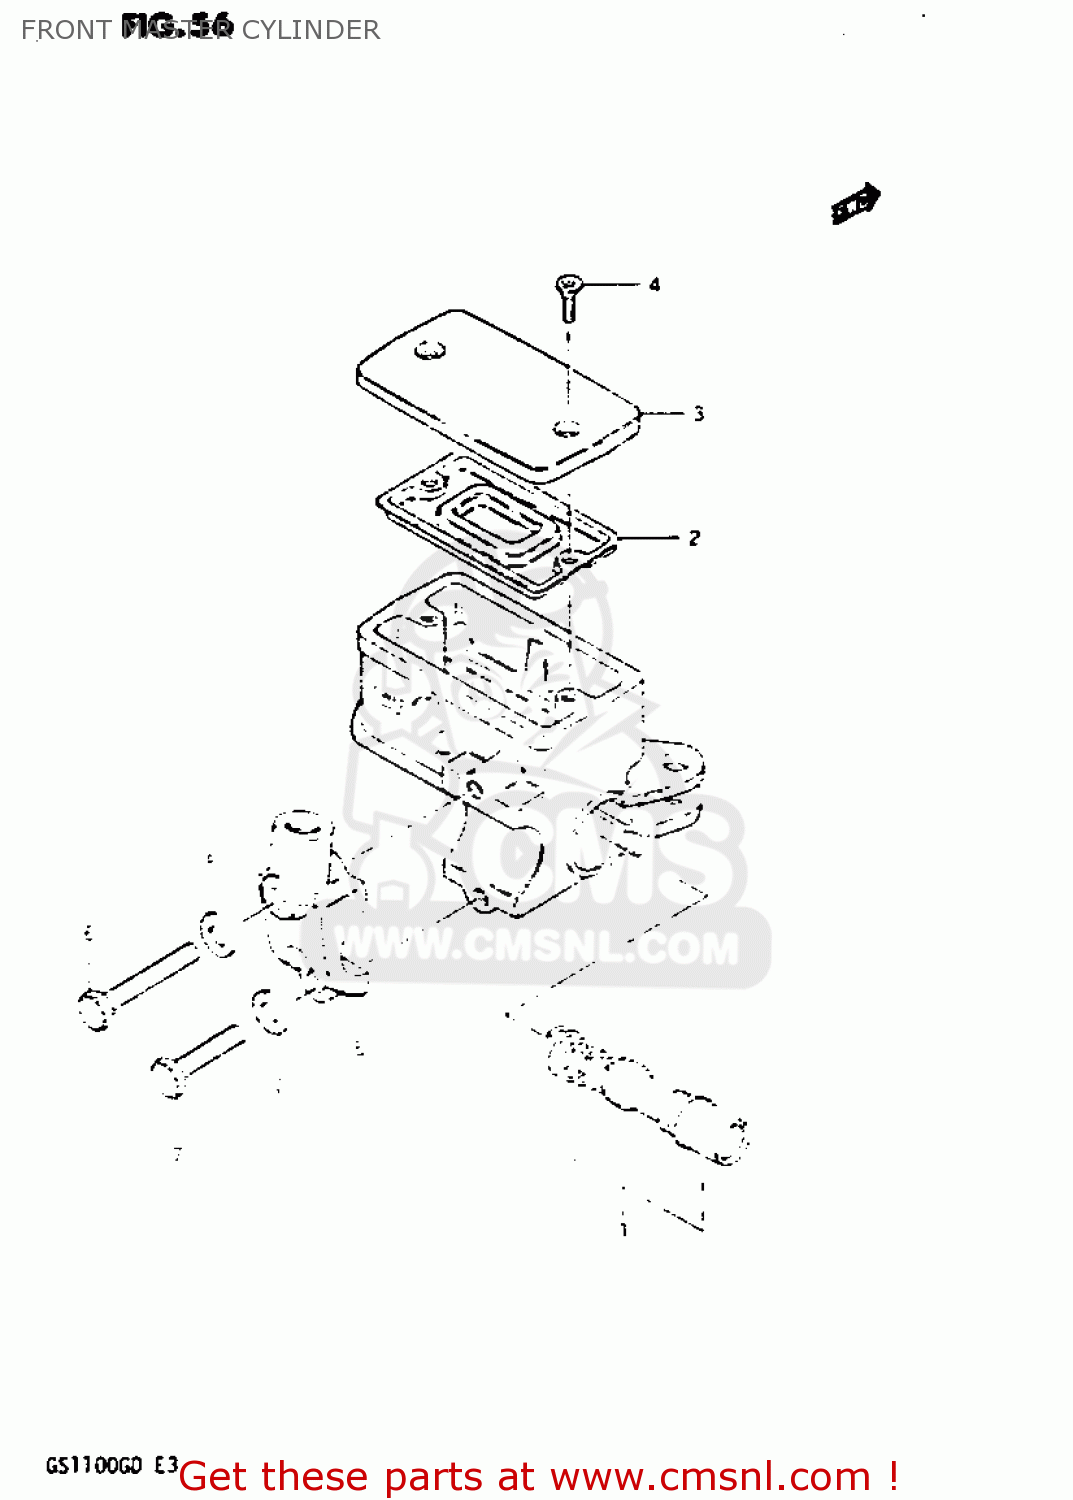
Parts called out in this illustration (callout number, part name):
1	PISTON & CUP SET
2	3
3	CAP
4	SCREW
5	HOLDER
6	BOLT 6X40
7	BOLT
8	WASHER
